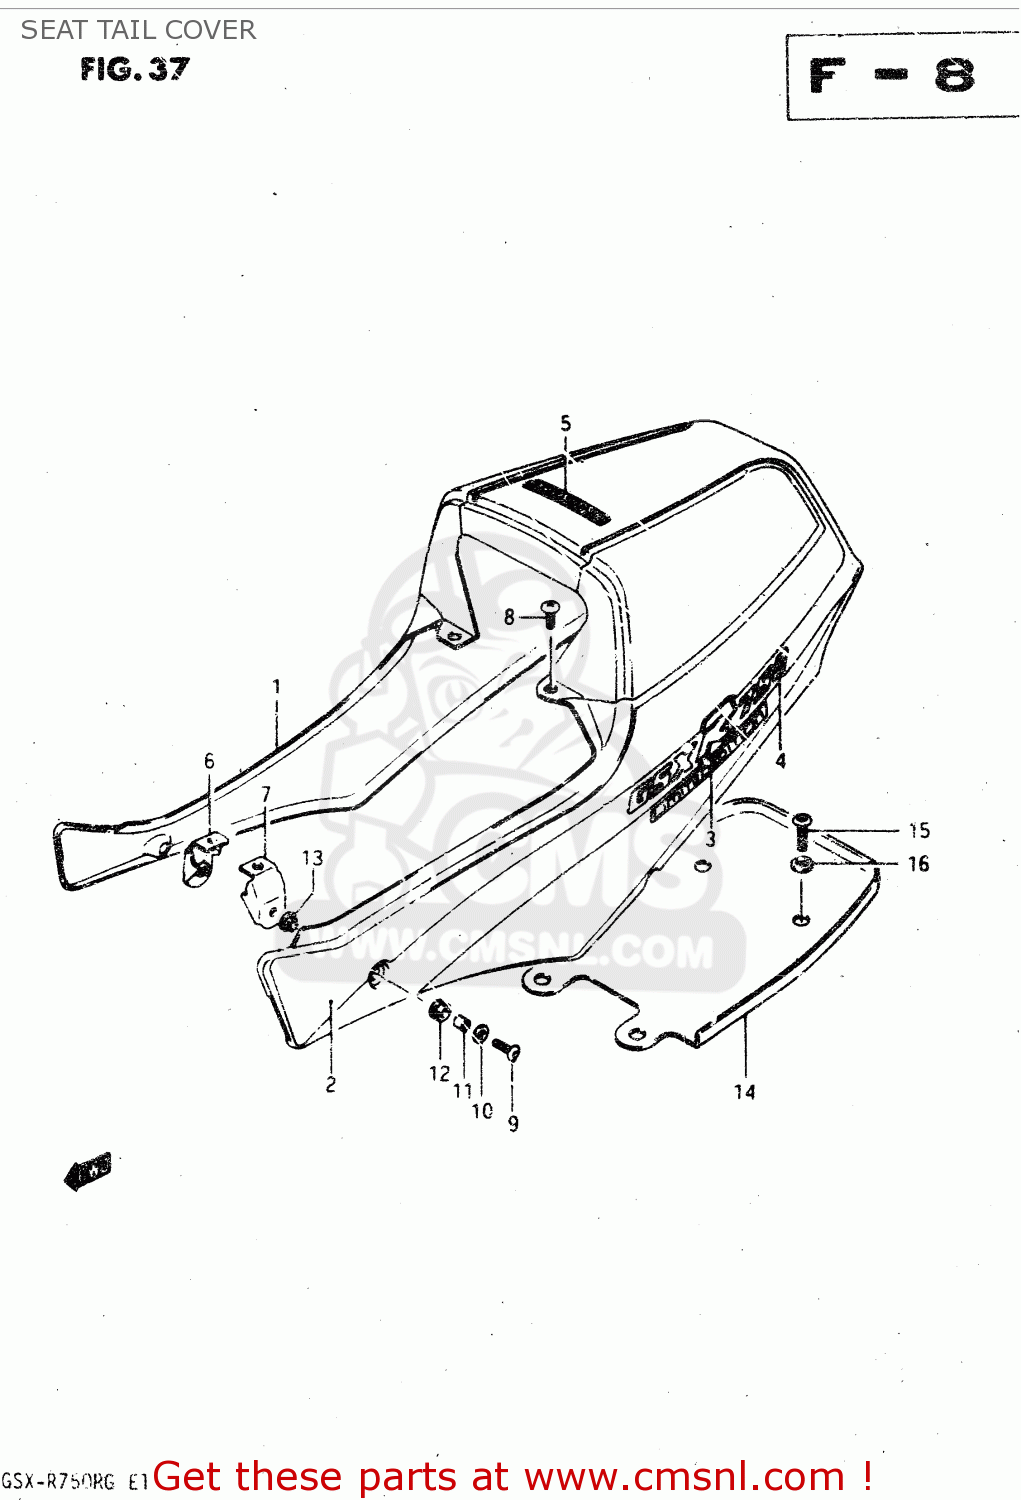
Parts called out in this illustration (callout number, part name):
1	COVER,SEAT TAIL
2	TAPE SET,BOX SEAT TAIL
3	EMBLEM (LIMITED EDITION)
4	EMBLEM,SEAT TAIL COVER
5	EMBLEM
6	HOLDER COMP,SEAT TAIL
7	HOLDER COMP,SEAT TAIL
8	SCREW
9	SCREW(6X20)
10	WASHER(6.5X18X1)
11	SPACER
12	CUSHION
13	WASHER
14	BOTTOM, SEAT TAIL
15	SCREW(6X16)
16	WASHER
